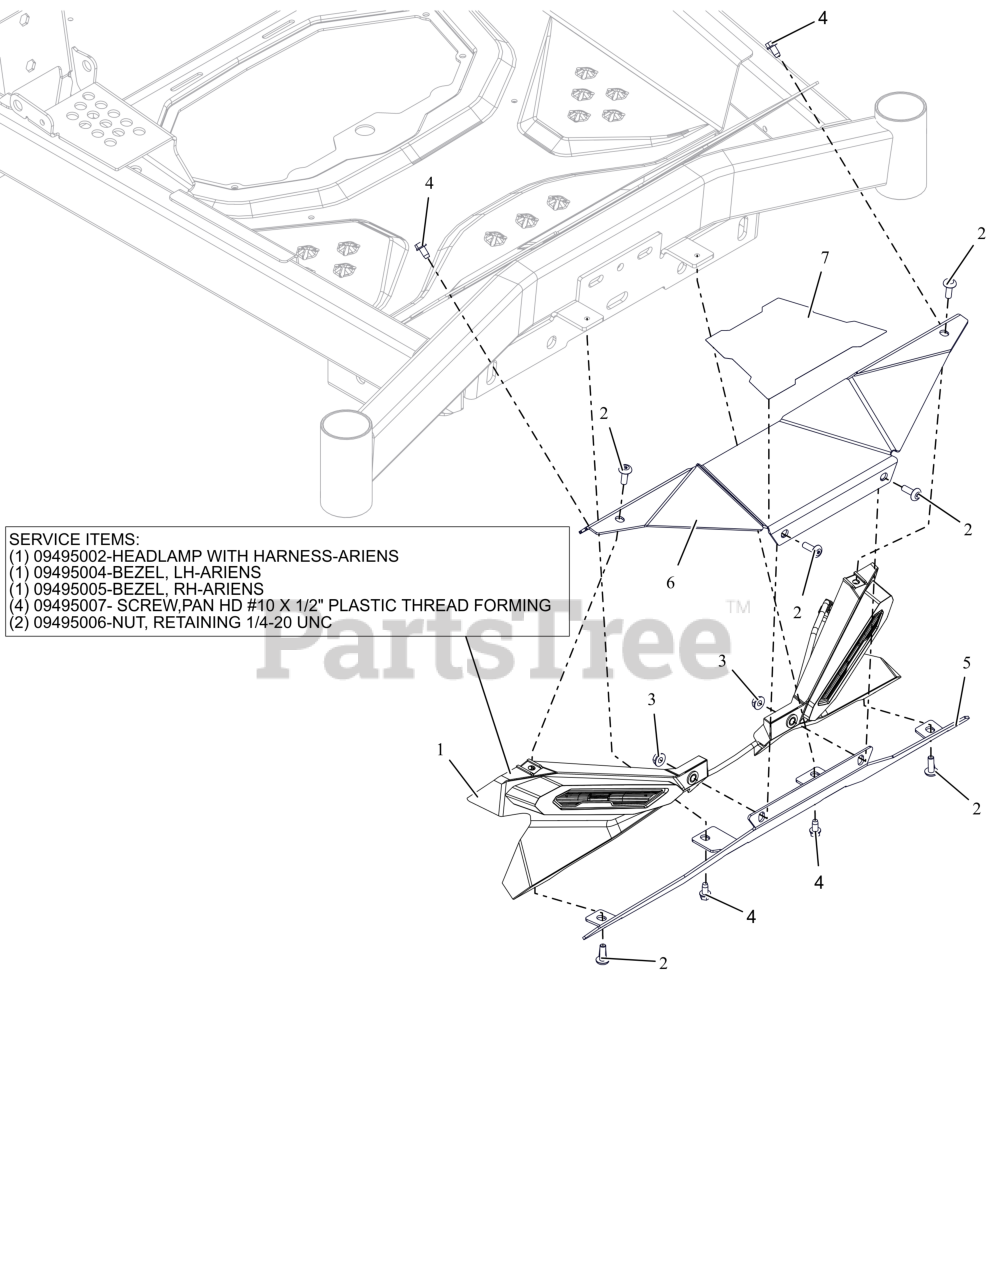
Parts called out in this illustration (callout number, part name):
1	LIGHT ASSY- HEADLIGHT-ARIENS
1	HEADLAMP- WITH HARNESS-ARIENS
1	BEZEL- ARIENS LH
1	BEZEL- ARIENS RH
1	SCR-.250-20 PAN HEAD-BSP210008
1	NUT- RETAINER .250-20 BLZINC
2	SCR-MCH .25-20X.75 TXTR ZB500
3	NUT-LK-CTR-FLG .25-20 ZC120
4	SCR-TAP .25X.50 HWH ZB500
5	PLATE- LOWER BEZEL MTG-ARIENS
6	FOOTREST-FRONT - ARIENS
7	GRIP- TAPE-FRONT STEP-ARIENS
